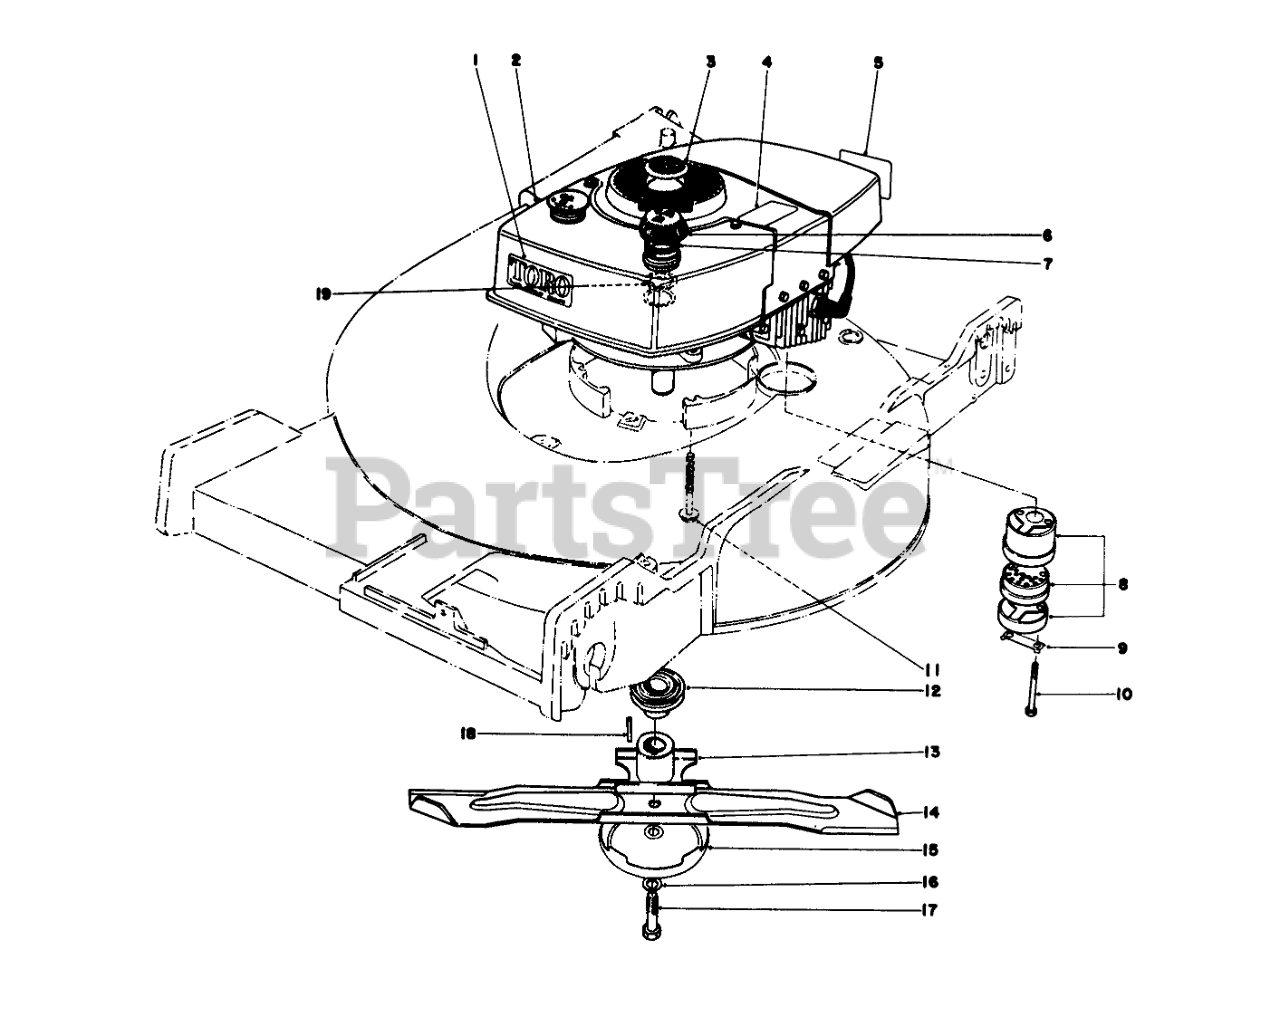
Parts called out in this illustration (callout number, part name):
1	High Torque
2	Engine
3	PLUG BUTTON
4	Decal Lockout
5	Decal-Maintenan
6	Gas Cap Assembly(Incl. Ref. #7 & 19)
7	GASKET
8	Muffler Assembly (Incl. Ref.#9 & 10)
9	CLIP - LOCKING
10	SCREW-HH
11	3/8-16 X 2-3/4 CAPSCR
12	DRIVER PULLEY
13	BLADE RETAINER WA(BLACK)
14	Blade
15	AntiScalp Cup
16	WASHER-LOCK
17	BLADE SCREW
18	KEY-SQUARE
19	GAS CAP BAFFLE
